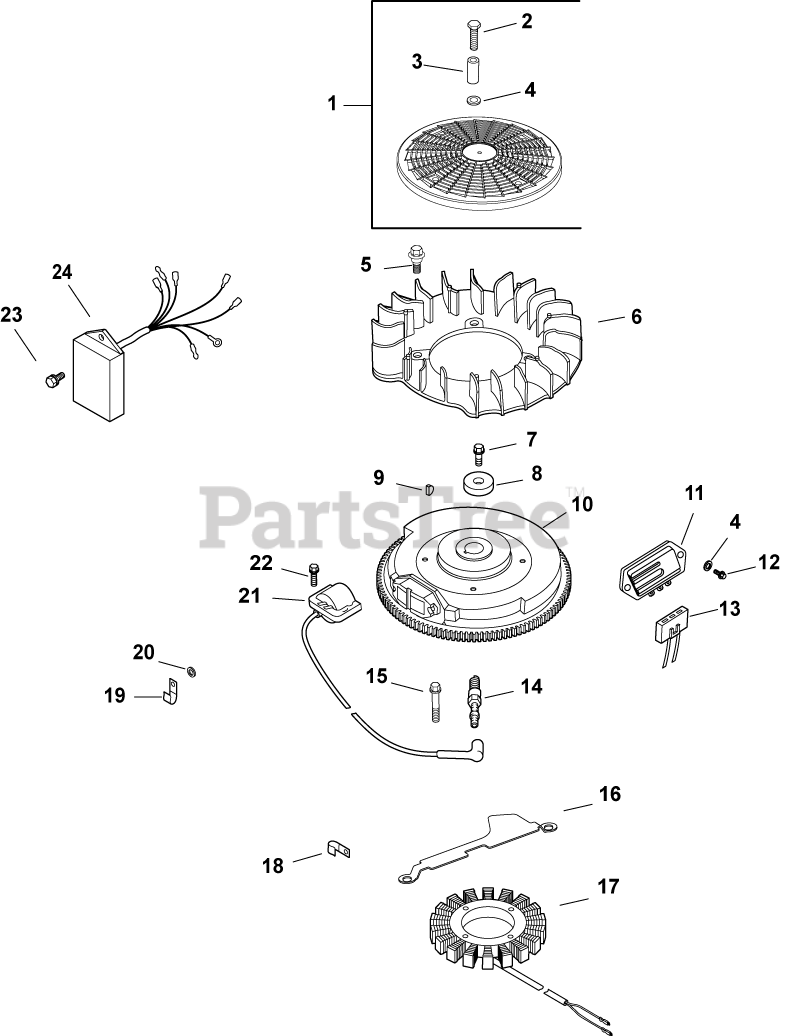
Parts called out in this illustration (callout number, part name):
1	KIT, GRASS SCREEN
2	SCREW, SLT HD CAP M4X0.7X25
3	SPACER - DISCONTINUED
4	WASHER, FLAT 3/16"
5	BOLT, SHOULDER
6	FAN (DOMED)-USE 24 157 17-S
7	SCREW, FLG M10X1.5X45 - (#25086361S)
8	WASHER, FLAT 13/32"
9	KEY, 3/16" X 5/8"
10	FLYWHEEL, PAINTED-USE 24 025 56-S
11	REG/RECT-15 AMP (KM)-USE 41 403 10-S
12	SCREW, PHL HD #11-16X7/8"
13	CONNECTOR, BODY (KM)-USE 25 155 41-S
14	PLUG, SPARK (PRO SERIES)
15	SCREW, M5X0.8X25 - (#25086402S)
16	BRACKET, STATOR WIRE
17	KIT, 15 / 20 AMP STATOR
19	CLIP, CABLE
20	WASHER, FLAT 1/4" (O.D. 1/2")
21	MODULE, IGNITION
22	SCREW, FLG THD FRM M5X.8X20-(#25086399S)
23	SCREW, THD FRM M4X0.7X10
24	MODULE, SPEED ADVANCE
2458452-S	MODULE, SPARK ADV -USE 24 584 89-S
